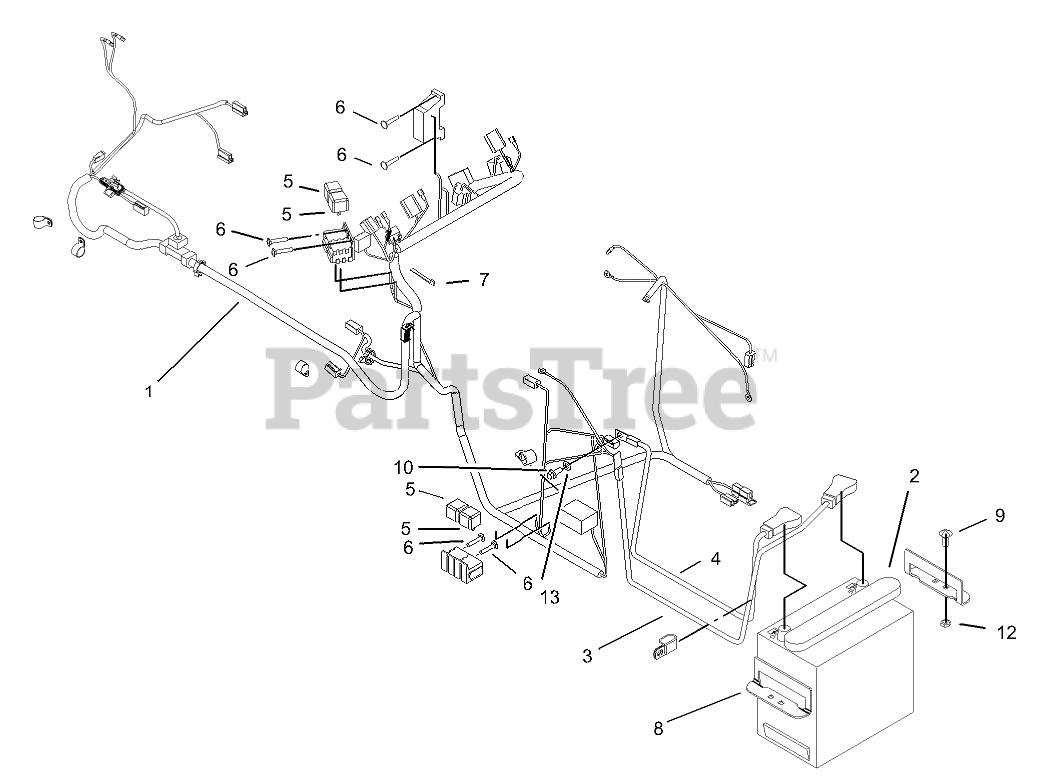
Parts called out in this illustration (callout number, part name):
1	Harness-Main
2	BATTERY - 495CCA
3	CABLE - BATTERY,RED
4	CABLE - BATTERY,
5	RELAY
6	SCREW-HWH
7	TIE-CABLE
8	HOLD - DOWN, BATTERY
9	SCREW-CARR
10	SCREW-HH
12	NUT-LOCK, NI
13	WASHER-LOCK
